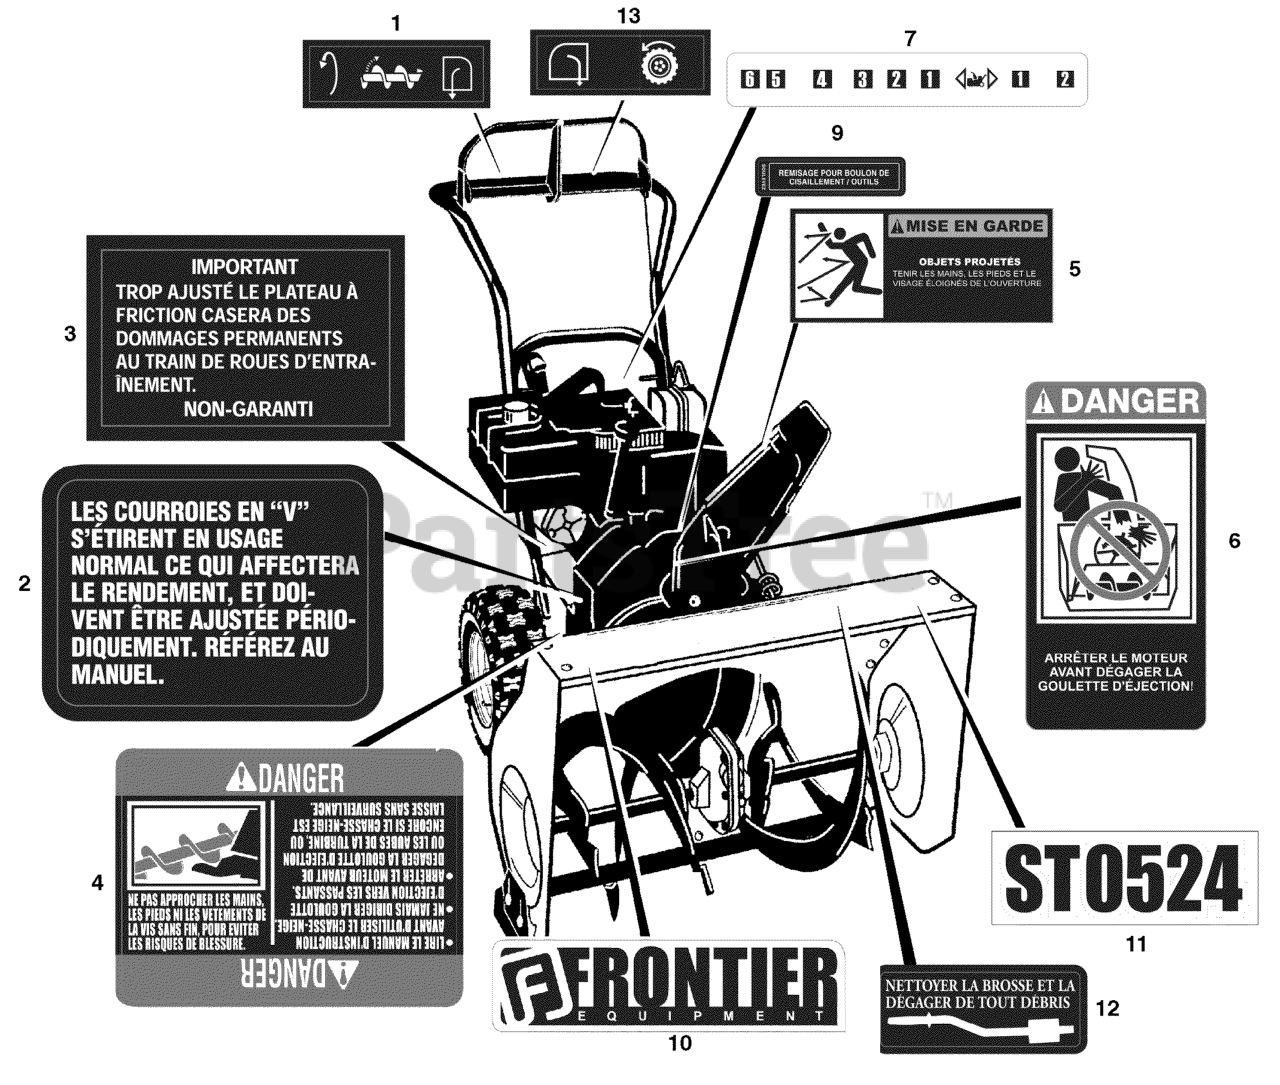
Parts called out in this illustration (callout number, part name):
1	DECAL, AUGER CONTROL
2	DECAL, V-BELTS
3	DECAL, OVER ADJUSTMENT
4	DECAL, ROTATING AUGER
5	DECAL, THROWN OBJECTS
6	DECAL, UNCLOGGING CHUTE
7	DECAL, SPEED CONTROL
9	DECAL, SHEAR BOLTS
10	DECAL, LOGO, FRONTIER
11	DECAL, ST0524
12	DECAL, CLEAN & CLEAR BRUSH
13	DECAL, TRACTON CONTROL
